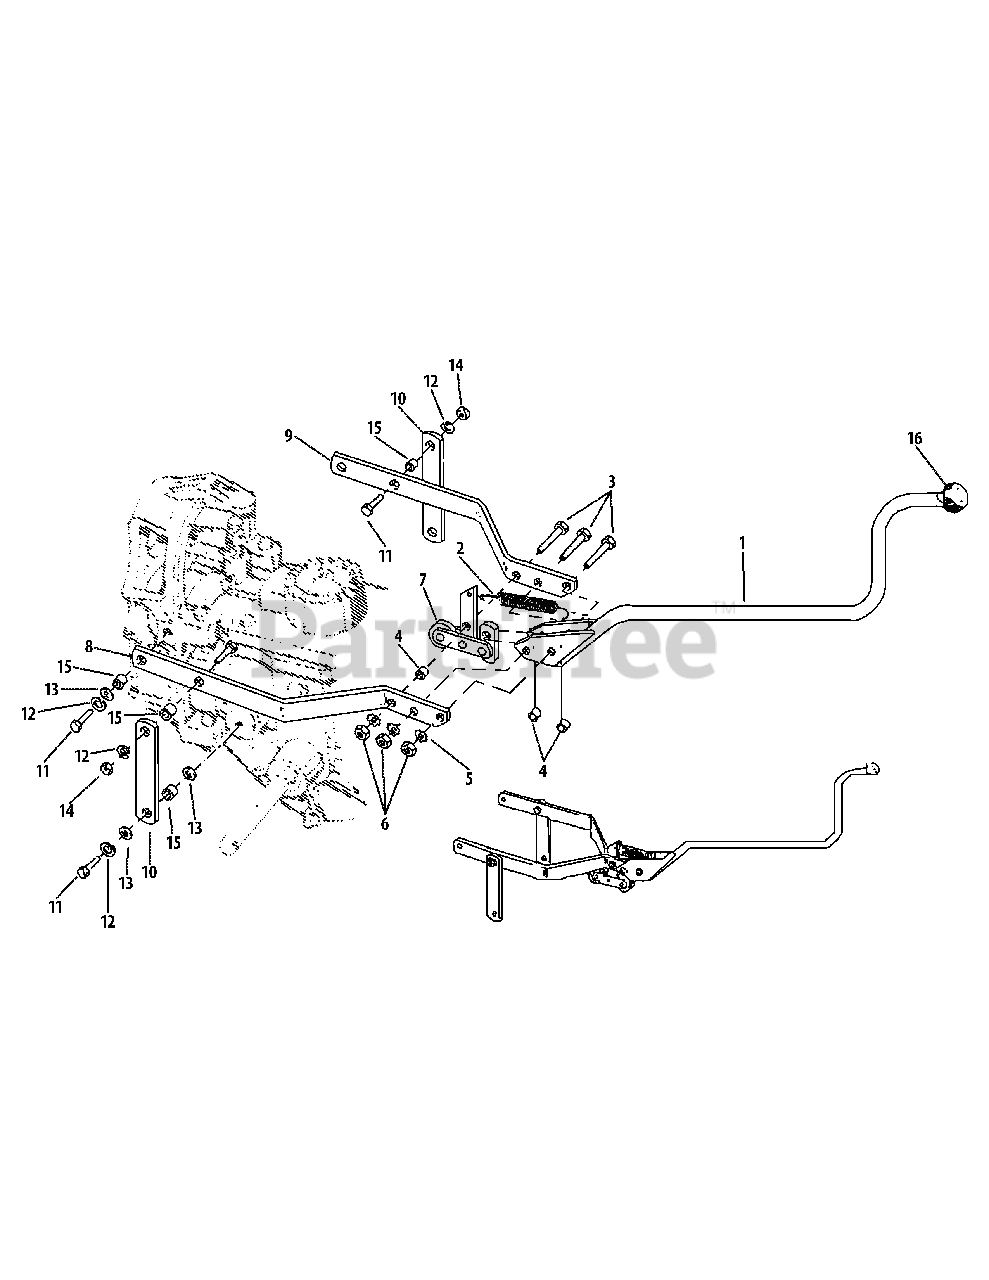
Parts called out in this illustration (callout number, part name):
1	Forward/Reverse Lever
2	Clutch Pawl Spring
3	Hex Bolt, 5/16-18 x 1-1/2"
4	Bushing, 3/8 "
5	External Tooth Lockwasher, 5/16"
6	Hex Nut, 5/16"-18
8	Yoke (Left)
9	Yoke (Right)
10	Yoke Pivot Link, 6- / "
11	Hex Bolt, 3/8 -16 x 1"
12	Spring Lockwasher, 3/8 "
13	Flat Washer, 3/8 "
14	Hex Nut, 3/8"-16
15	Bushing Spacer, 19/64"
16	Knob
